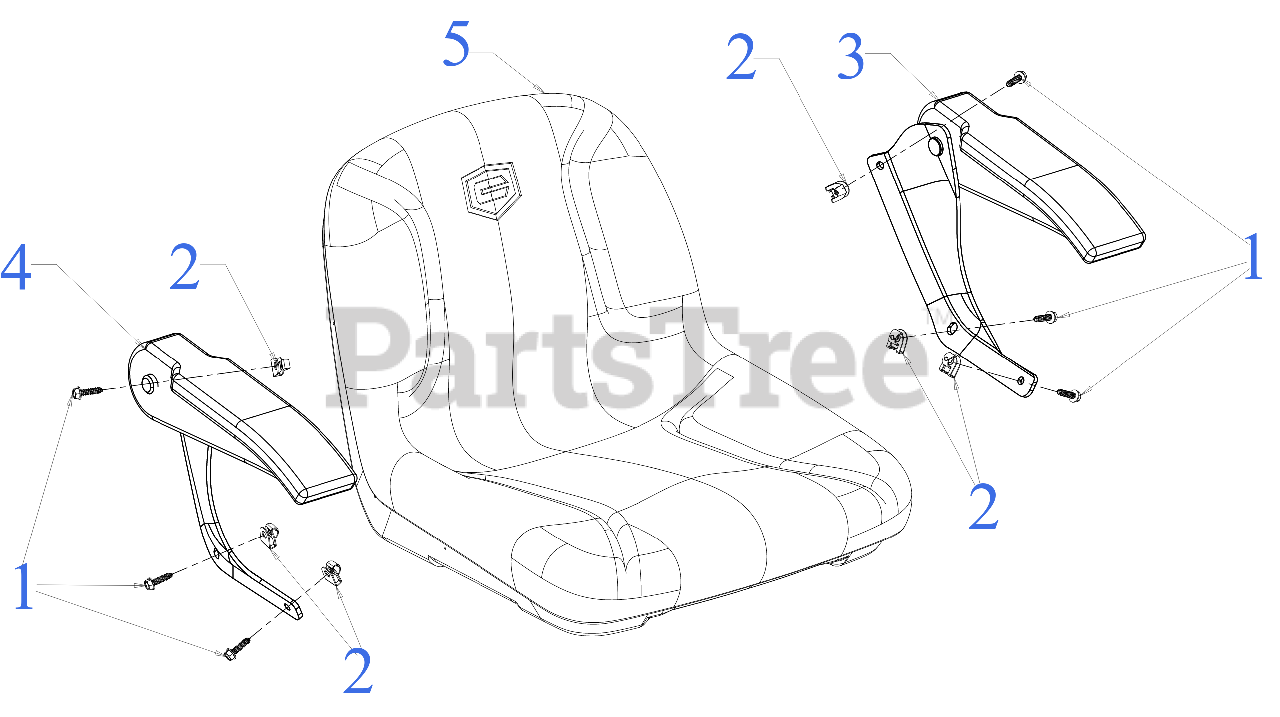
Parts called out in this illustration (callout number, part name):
1	SCREW 1/4-14X 1.00
2	ARMREST SPEED NUT
3	LH & RH ARMREST KIT
4	LH & RH ARMREST KIT
5	HIGH BACK SEAT CRAFTSMAN
